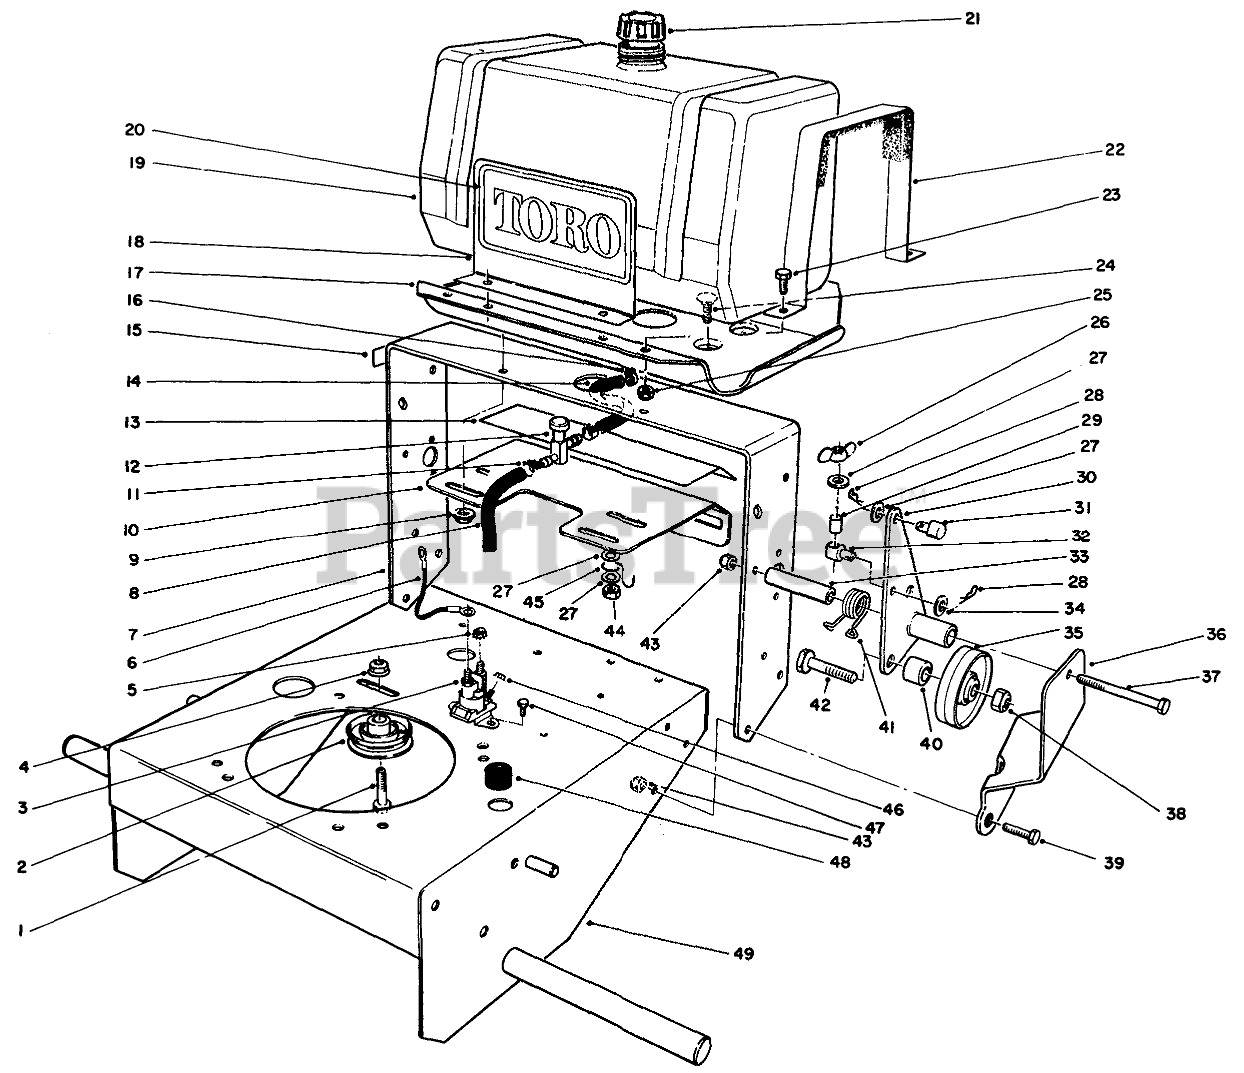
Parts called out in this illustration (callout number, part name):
1	SCREW-HH
2	Pulley Idler
3	Solenoid
4	NUT-HF
5	NUT-KEPS
6	WIRE-SOLENOID/STARTER
7	Frame-Rear
8	GAS HOSE
9	NUT-HF
10	Plate
11	CLAMP-HOSE
12	FUEL VALVE
13	Decal-Ground Speed
14	HOSE-FUEL
15	Decal-Fuel Shut Off
16	CLAMP-WORM
17	PLATE-FUEL TANK
18	DECAL-PLATE
19	TANK-FUEL
20	DECAL
21	GAS CAP ASM
22	STRAP ASM
23	SCREW-HH
24	SCREW-CARR
25	NUT-LOCK, NI
26	NUT-WING
27	WASHER-PLAIN
28	PIN-COTTER
29	BUSHING-NYLON
30	Bracket-Idler, LH
31	Fitting-Rod
32	FITTING-ROD
33	PIVOT-IDLER SPACER
34	WASHER-PLAIN
35	IdlerWheel
36	Bracket-LH
37	SCREW-HH
38	NUT-LOCK, NI
39	SCREW-HH
40	WHEEL IDLER SPACER
41	SPRING-TORSION, LH
42	SCREW-LEVELER
43	NUT-LOCK, NI
44	NUT-LOCK, NI
45	Clip-Gas Line
46	NUT-KEPS
47	SCREW
48	GROMMET
49	Frame
